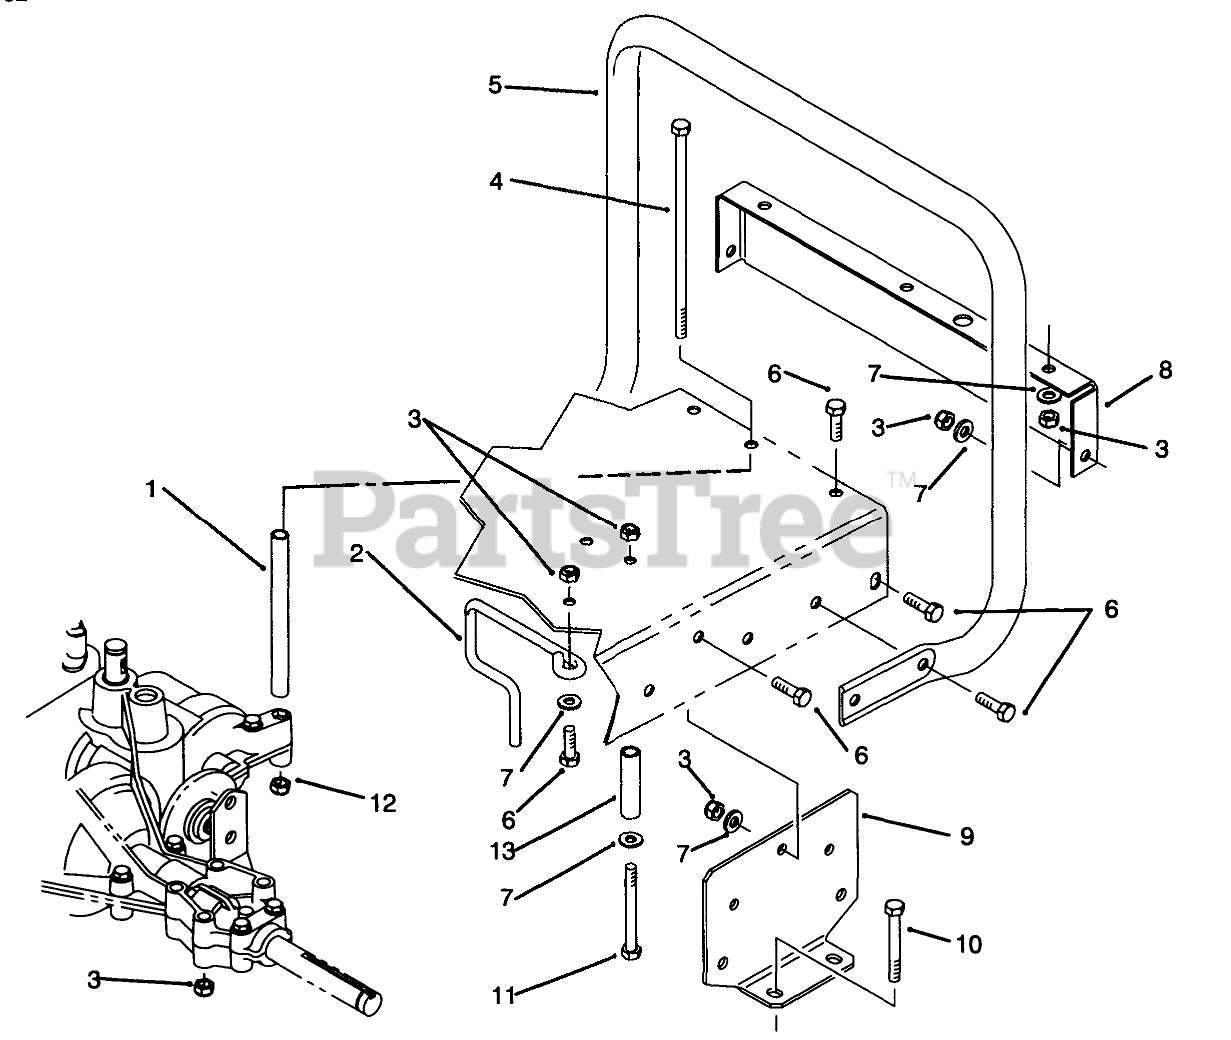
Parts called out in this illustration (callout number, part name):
1	SPACER-TRANSAXLE SUPT
2	GUIDE-ENG BELT
3	NUT-LOCK, NI
4	SCREW-HH
5	Standbar
6	SCREW-HH
7	WASHER-PLAIN
8	Frame-Rear
9	Support-Axle
10	SCREW-HH
11	SCREW-HH
12	NUT-LOCK, NI
13	SPACER-SPLIT TUBE
